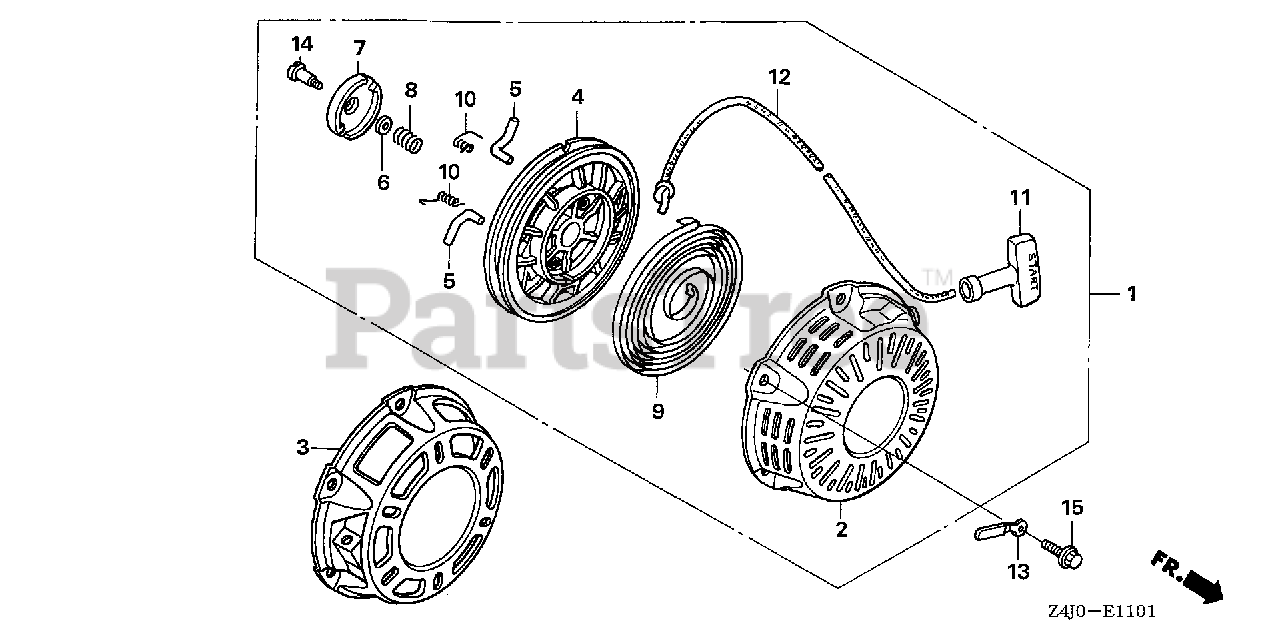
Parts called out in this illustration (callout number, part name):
1	STARTER ASSY., RECOIL *NH1* (BLACK)
1	STARTER ASSY., RECOIL *R280* (POWER RED)
2	CASE, RECOIL STARTER *R280* (POWER RED)
2	CASE, RECOIL STARTER *NH1* (BLACK)
4	REEL, RECOIL STARTER (BLACK)
5	RATCHET, STARTER
6	PLATE, FRICTION
7	GUIDE, RATCHET
8	SPRING, FRICTION
9	SPRING, RECOIL STARTER
10	SPRING, RETURN
11	GRIP, STARTER
11	KNOB, RECOIL SRARTER
12	ROPE, RECOIL STARTER
14	SCREW, SETTING
15	BOLT, FLANGE (6X10)
